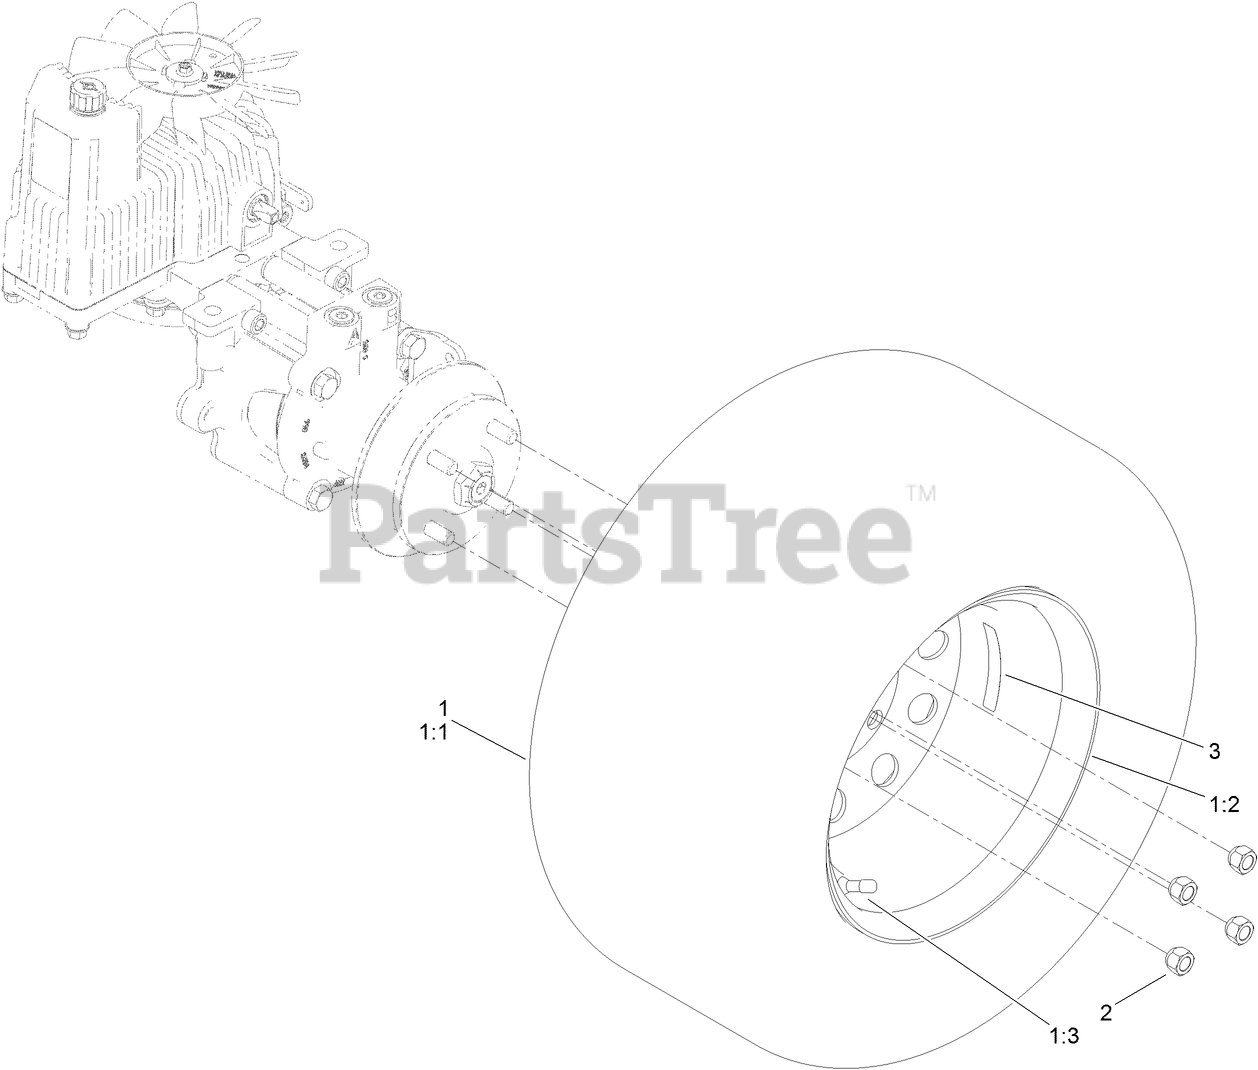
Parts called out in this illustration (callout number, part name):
1	WHEEL AND TIRE ASM
2	NUT-LUG
3	DECAL-WHEEL HUB
